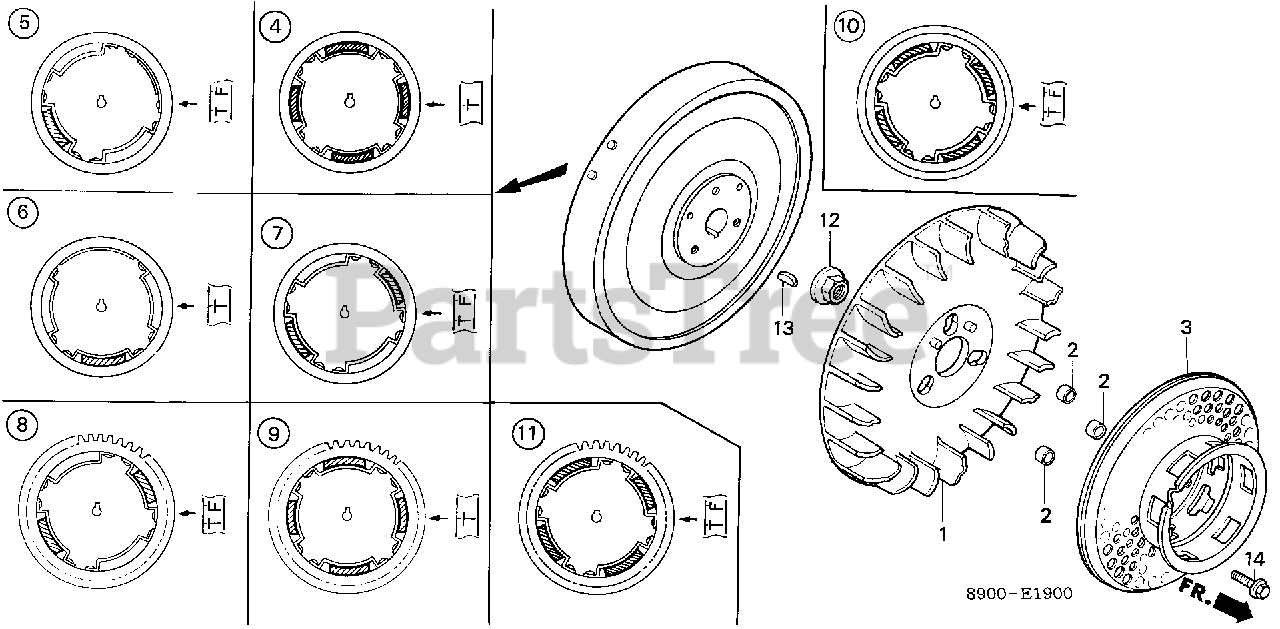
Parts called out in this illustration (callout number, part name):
1	FAN, COOLING
2	COLLAR, FAN
3	PULLEY, STARTER
3	PULLEY, STARTER (NOT AVAILABLE)
6	FLYWHEEL (C.D.I.)
9	FLYWHEEL (C.D.I.+STARTER) (NOT AVAILABLE)
11	FLYWHEEL (STARTER+RECTIFIER)
12	NUT, SPECIAL (16MM)
13	KEY, SPECIAL WOODRUFF (25X18)
14	BOLT, FLANGE (6X16)
